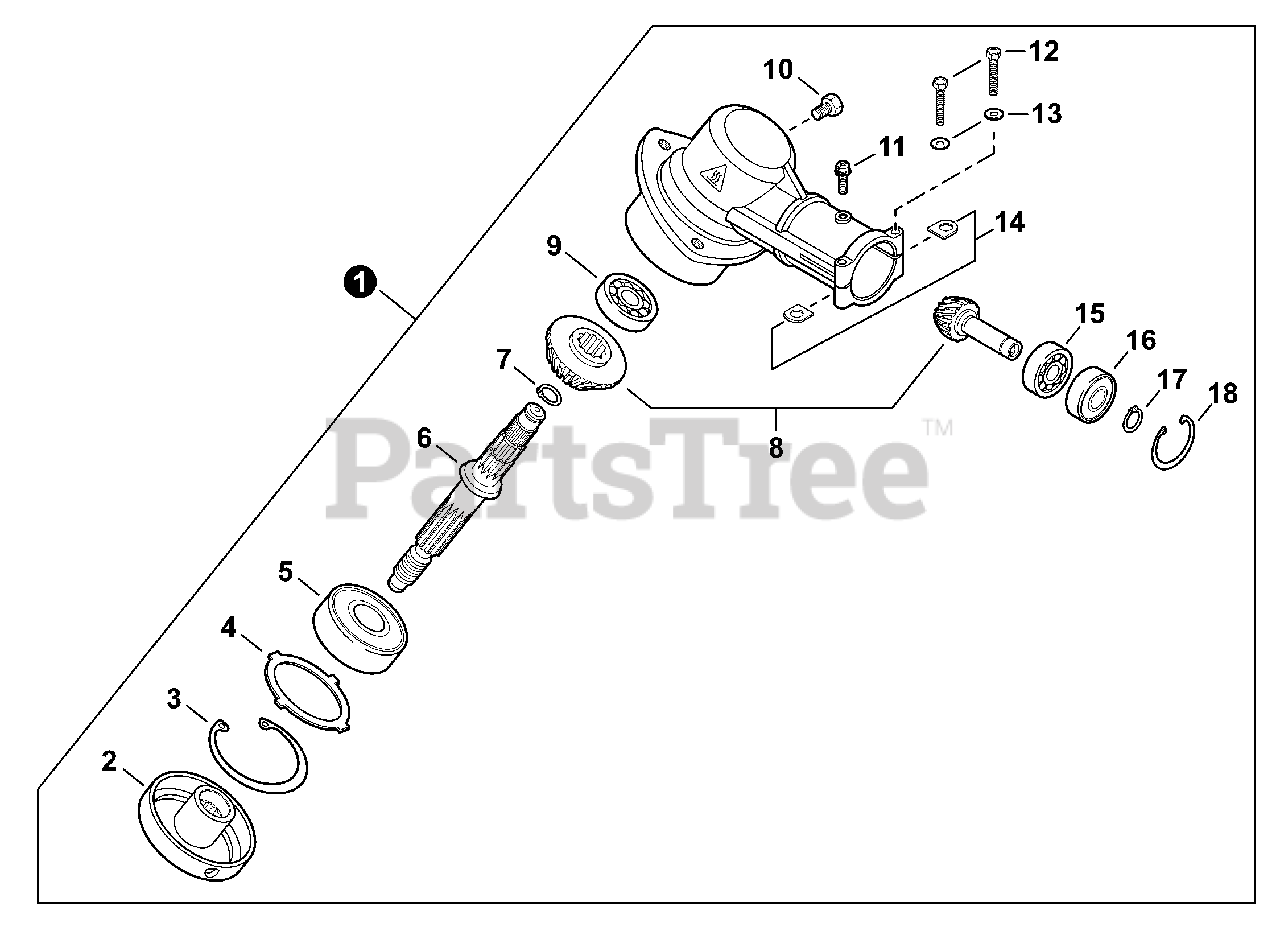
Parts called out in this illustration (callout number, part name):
1	GEAR CASE ASSY
2	PLATE, ADAPTOR - UPPER
3	RING, SNAP Ø32
5	BEARING, BALL 6201
6	SHAFT, GEAR
7	RING, SNAP Ø12
8	GEAR SET
9	BEARING, BALL 609
10	BOLT M8×8
11	SCREW 5×10
12	BOLT 5×35 SP
13	WASHER, FLAT 5.5×10×0.8
14	D-WASHER
15	BEARING, BALL 6900
16	BEARING, BALL 6900Z
17	RING, SNAP Ø10
18	RING, SNAP Ø22
